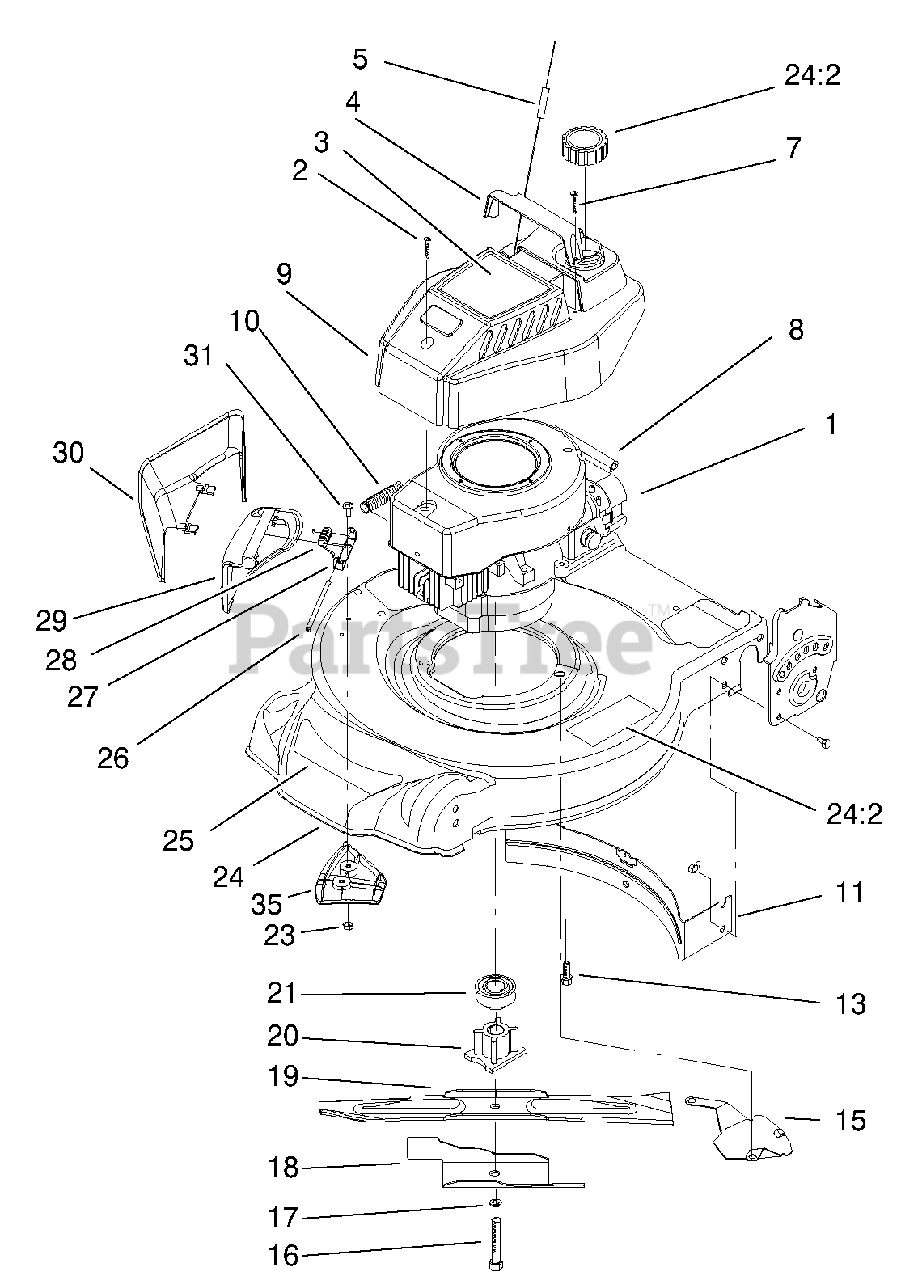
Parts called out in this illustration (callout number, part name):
3	Decal-Recoil
4	Strap-Tank
5	Stop-Rope
6	Gas Cap Assembly
7	Screw-PPH
8	Fuel Line
9	Tank/Shroud
10	Spring-Compression
11	Baffle-Rear
13	Screw-Taptite W/Patch
15	Shield-Grass
16	Screw-Blade
17	Washer-Lock
18	Accelerator
19	Blade-21",Rec,Gen.ii
20	Blade Retainer
21	Pulley-Driver
24:2	Decal-Danger
25	Decal-Deck
26	Rod-Cover
27	Bracket-Cover
28	Spring-Torsion
29	Cover-Side
30	Chute-Side
31	Screw-CARR
